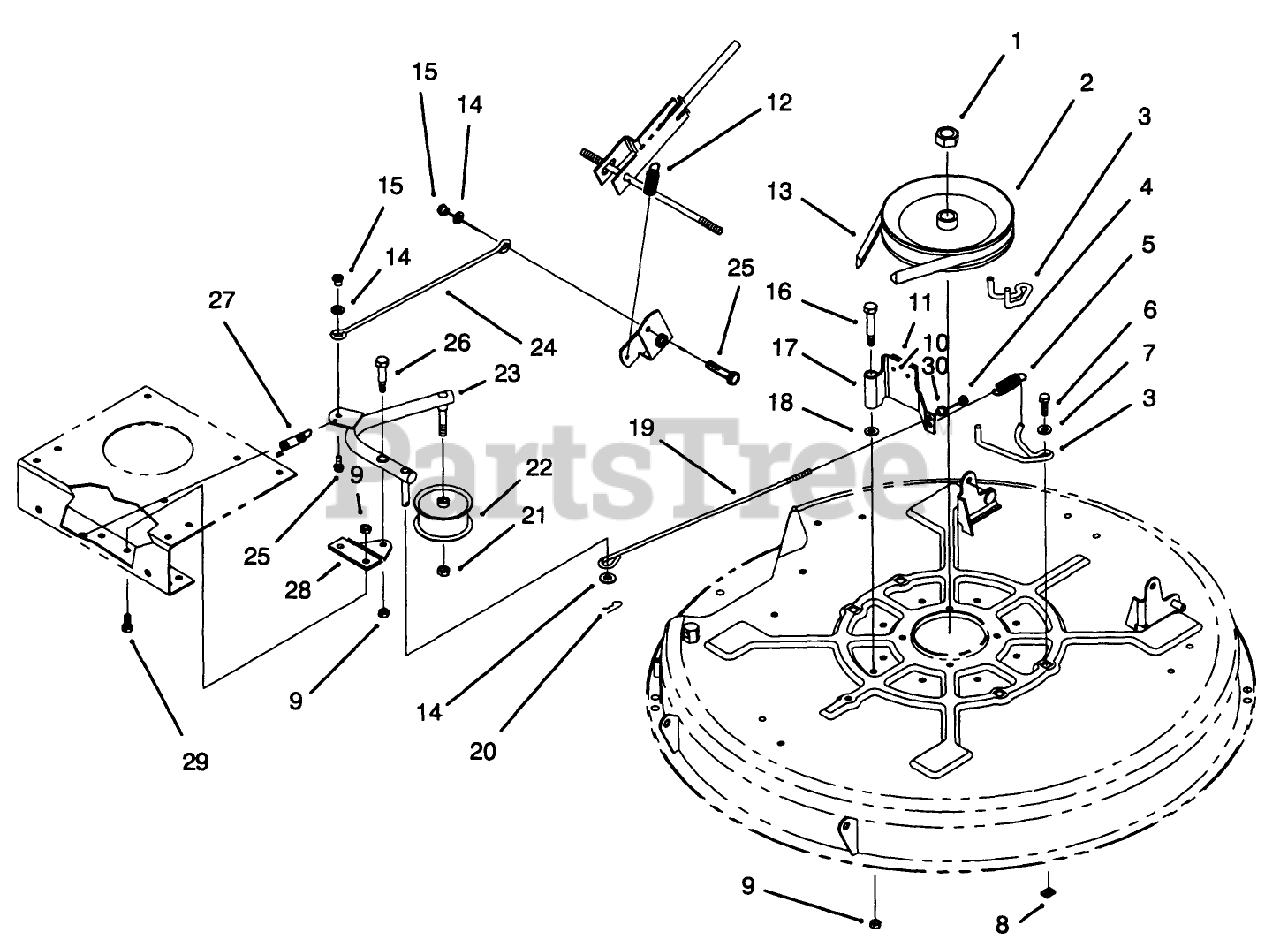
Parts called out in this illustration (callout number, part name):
1	NUT-HEX
2	PULLEY-DECK
3	GUIDE-BELT, DECK
4	NUT-LOCK, NI
5	SPRING-EXTENSION
6	SCREW-HH
7	WASHER-PIVOT
8	NUT-RETAINER
9	NUT-LOCK, NI
10	RIVET-BLIND
11	PAD-BRAKE
12	CABLE SPRING ASM
13	V-BELT
14	WASHER-FLAT
15	POST-MOUNTING, LINKAGE
16	BOLT-SHOULDER
17	BRAKE ARM ASM
18	WASHER-PLAIN
19	ROD-BRAKE, DECK
21	NUT-LOCK, NI
22	PULLEY-IDLER
24	ROD-ENGAGE, DECK
25	SCREW-HHF
26	SCREW-SHOULDER, HH
27	SPRING-RETURN, BRAKE
29	SCREW-HH
30	BALL-SWIVEL, STOP
